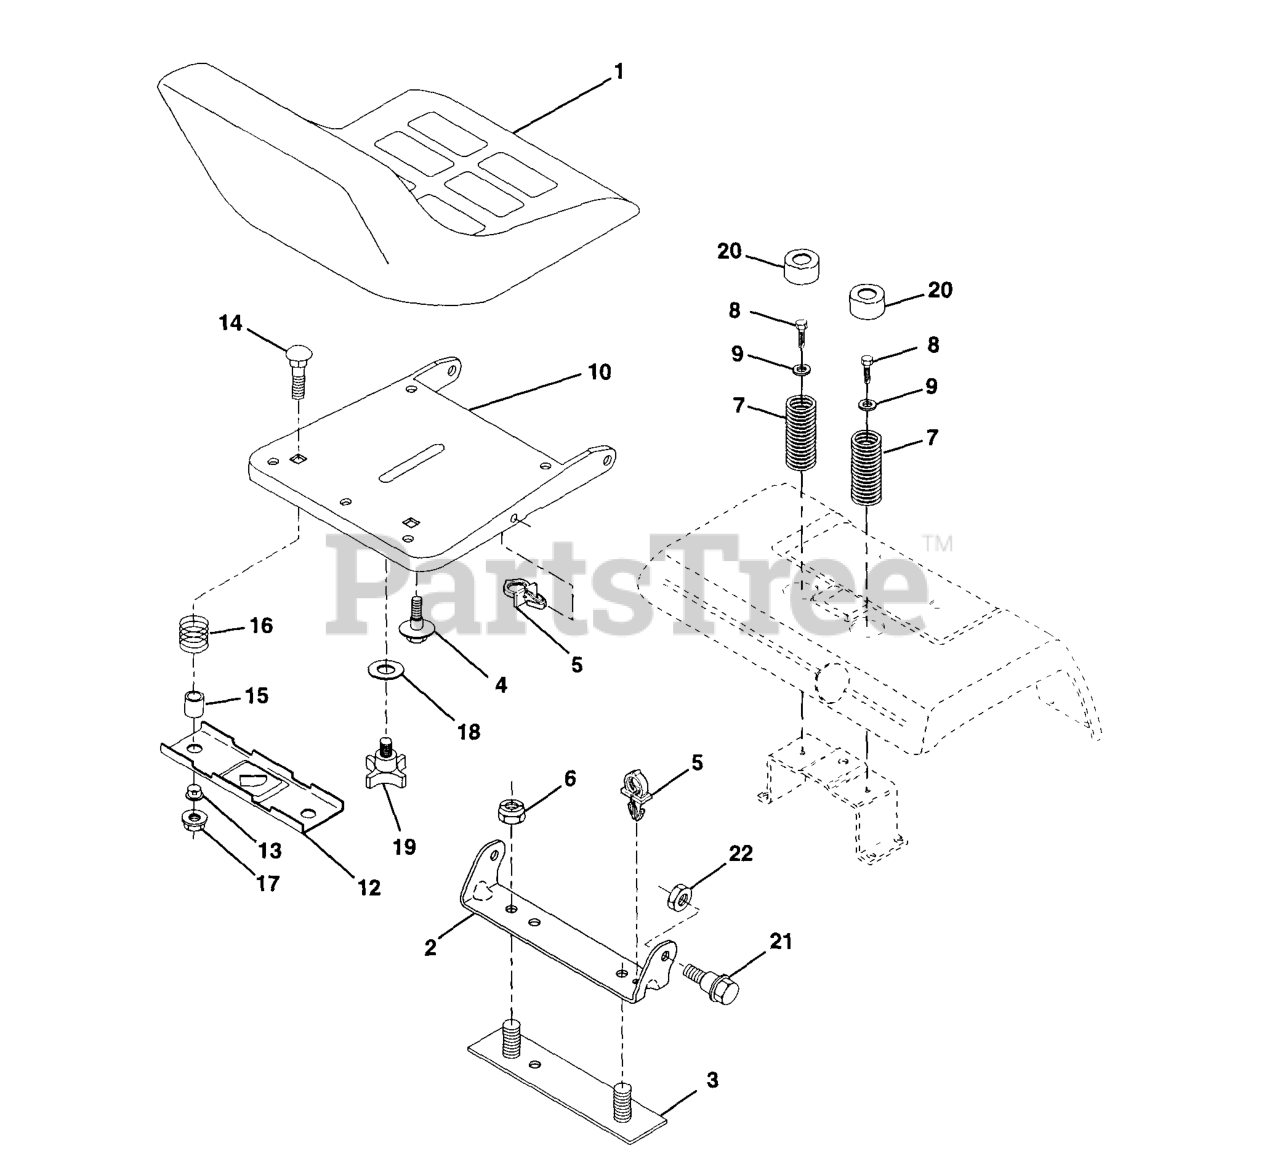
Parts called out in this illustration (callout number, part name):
1	SEAT
2	SEAT PIVOT BRKT
3	STRAP
4	BOLT,SHOULD
5	INSULATED CLIP
6	NUT
7	SPRING COMPRESSION
8	Screw, Thdrol 5/16-18 X 1/2
9	WASHER
10	SEAT PAN
12	BRKT SWITCH
14	Bolt, Carriage 1/4-20 X 1-3/8
15	SPACER SPLIT
16	SPRING COMPRESSED
17	NUT T
19	KNOB 1/2" YT
20	CAP SPRING
21	BOLT.SHOULDER.5/16-18
22	LOCKNUT
